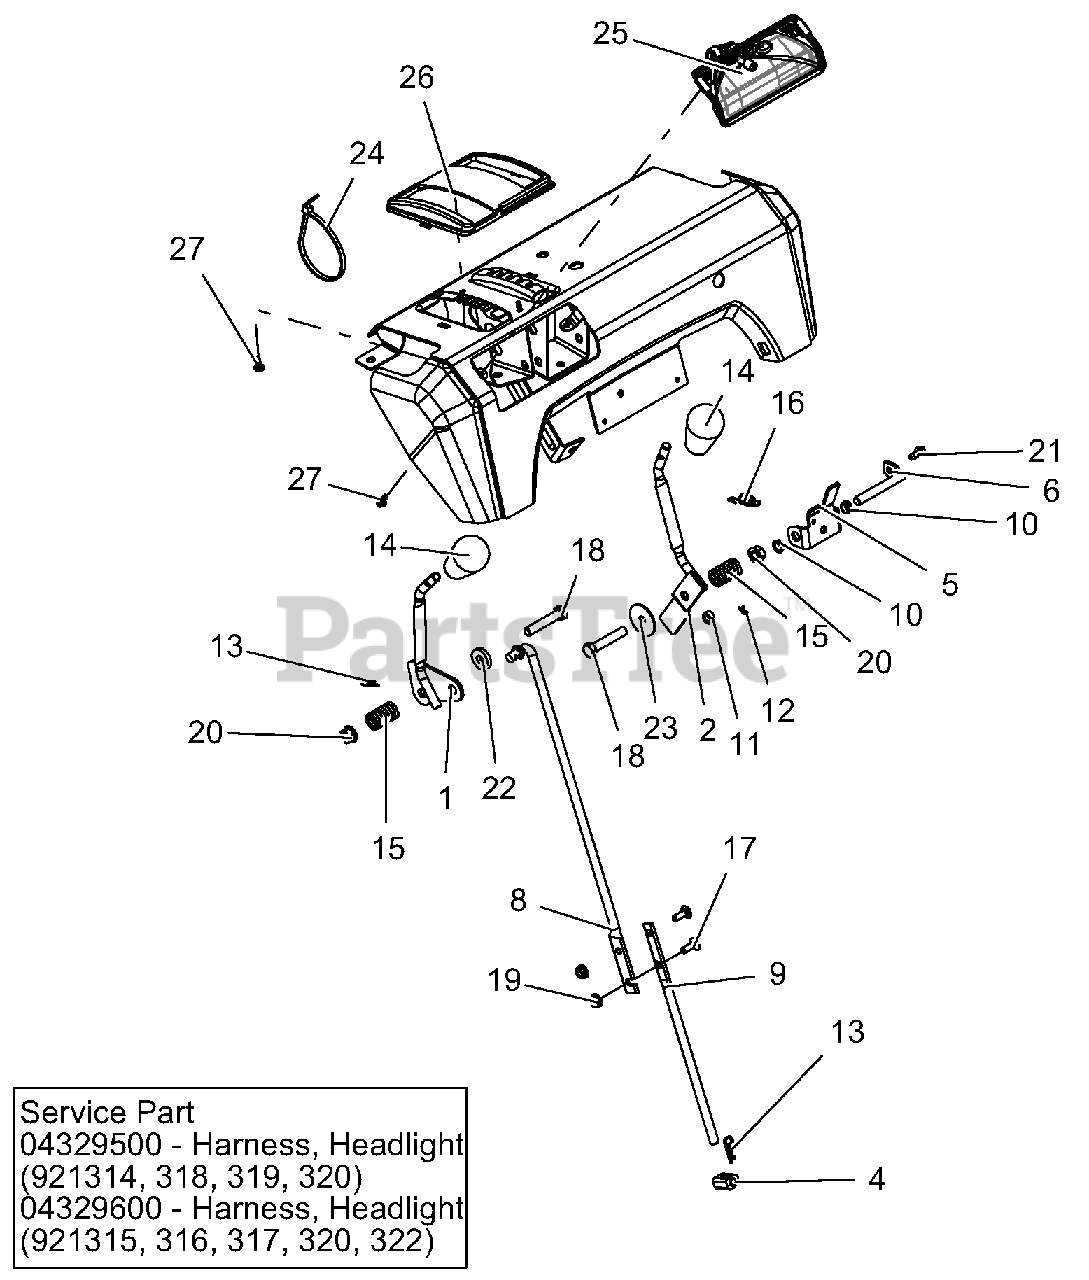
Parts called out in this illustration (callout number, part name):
1	WELDMENT, CONTROL LEVER(SHIFT)
2	WELDMENT, CONTROL LEVER (DEFL)
4	PIVOT,SHIFT ROD .375-16(TRUNN)
5	BRACKET, INTERLOCK ARM
6	ROD, PIVOT - INTERLOCK
8	ROD, SHIFT - UPPER
9	ROD, SHIFT - LOWER
10	BUSHING, POLYLINER-.38 SNAPIN
11	BSHG-SLV .265X.500X.219
12	PIN-HAIR INT .06X.18X.77
13	PIN-HAIR INT .08X.18X1.18 YWZC
14	KNOB,SOFT TEARDROP,PUSH-ON GRY
15	SG-COMP .125X.781X1.250
16	SPRING-EXT .047X.438X1.45
17	@BLT-RDHDSQNK .25-20X.75 G5YZ
18	@BLT-HEX .38-16X2.00 GR5 YWZC
19	@NUT-LK-CTR-FLG .25-20 YWZC
20	@NUT-LK-TOP-FLG .38-16 YWZC
21	SCR-TAP .25-20X.50 HWH TR YWZ
22	WSHR-FL-STL .406X1.00X.188 YWZ
23	WSHR-FL-STL .380X1.50X.062 YWZ
24	CABLE TIE LG 5-1/2
25	HEADLIGHT ASSY, HALOGEN 20W
26	BEZEL, SHIFT
27	SCR-TAP #10X.50 BOSS INDHXHD
